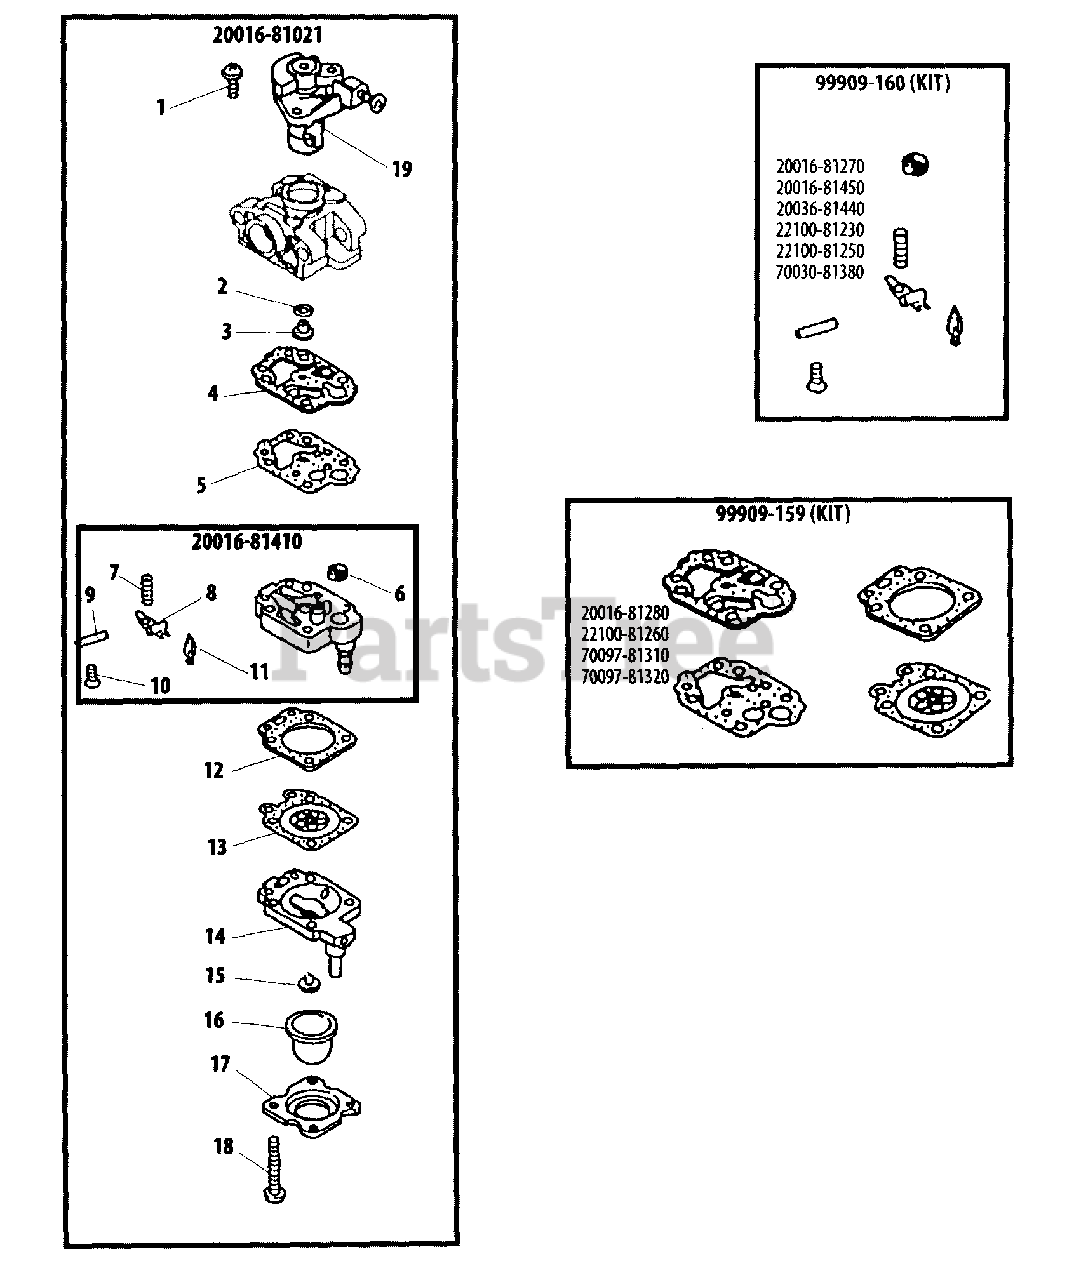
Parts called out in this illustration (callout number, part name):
1	SCREW
2	O-RING
3	JET, MAIN
4	GASKET, PUMP
5	DIAPHRAGM, PUMP
6	STRAINER
7	SPRING, METERING LEVER
8	LEVER, METERING
9	PIN, METERING LEVER
10	SCREW, METERING LEVER PIN
11	VALVE, INLET NEEDLE
12	GASKET, METERING
13	DIAPHRAGM, METERING
14	BASE, PURGE
15	VALVE, CHECK
16	BULB, PURGE
17	RETAINER, PURGE BULB
18	SCREW, PUMP COVER
19	VALVE, THROTTLE
20016-81021	CARBURETOR
20016-81410	PUMP BODY ASSY
99909-159	DIAPHRAGM/GASKET KIT
99909-160	REPAIR KIT
